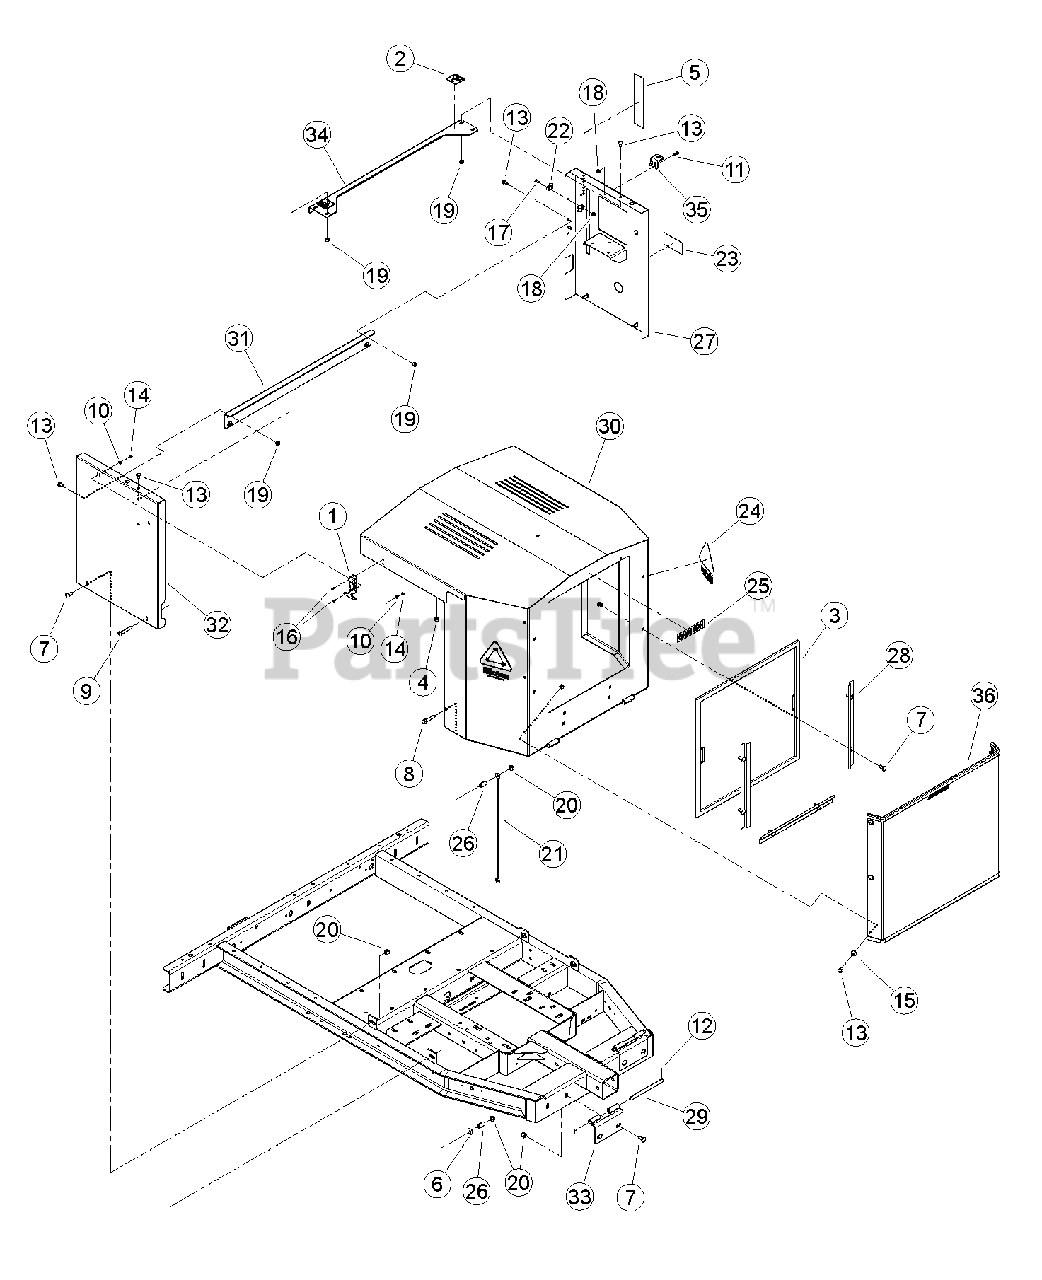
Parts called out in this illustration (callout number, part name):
1	LATCH, FLEXIBLE DRAW
2	DECAL, SHIELD DANGER ISO
3	SCREEN, RADIATOR INLET
4	BUMPER, RUBBER
5	DECAL, CHIPPER ENGAGEMENT
6	WASHER, 3/8" FLAT ZP
7	BOLT, 3/8 X 1" GR5 CRG NC ZP
8	BOLT, 3/8 X 2 FLANGE NC
9	BOLT, 3/8 X 2-1/2" GR5 CRG NC ZP
10	WASHER, 3/16" FLAT ZP
11	BOLT, 1/4 X 3/4 GR5 CRG ZP
12	ROLL PIN, 5/32 X 3/4" PLAIN
13	BOLT, 5/16 X 3/4 GR5 CRG NC ZP
14	NUT, 10/24 NYLOCK TYPE NM ZP
15	WASHER, 5/16" ID 7/8" OD NYLON FLAT
16	SCREW, MCH 10-24 X 1/2" PAN HD PH ZP
17	RIVET, AL BLIND 1/4 X 3/4 DOME HEAD
18	NUT, 1/4-20 NYLOCK-FLANGE
19	NUT, 5/16-18 NYLOCK-FLANGE
20	NUT, 3/8-16 NYLOCK FLANGE
21	LANYARD, STEEL W/ PVC 1/8 X 20"
22	CLAMP, CABLE MOUNT
23	DECAL, FEED SPEED
24	DECAL, CHIP IT
25	DECAL, MODEL CH611DH
26	IDLER SPACER
27	WELDMENT, ENGINE RIGHT
28	BRACKET, SCREEN HOLDER
29	PIN, HOOD HINGE PLATED
30	WELDMENT, 6 INCH HOOD
31	PLATE, HOOD SUPPORT
32	SHIELD, ENGINE LEFT
33	WELDMENT, HOOD HINGE
34	BRACE, ENGINE SHIELD
35	BASE, HOOD LOCK
36	ASSEMBLY, 6 INCH SCREEN
